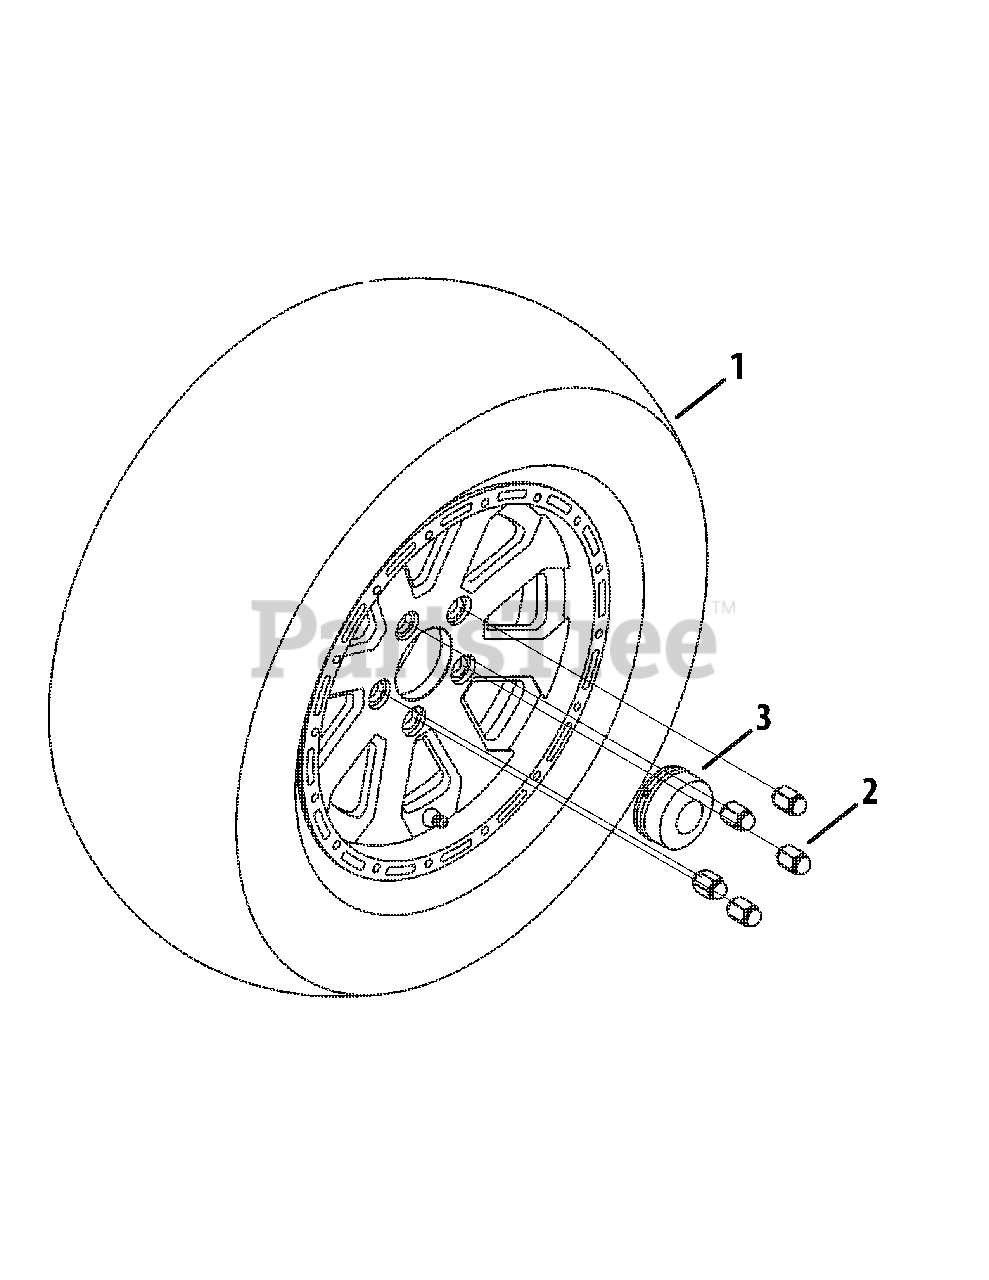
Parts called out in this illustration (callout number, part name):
1	Wheel Assy., 26 x 12-14, Rear/Left
1	Wheel Assy., 26 x 12-14, Rear/Right
1	Wheel Rim, 14 x 8, Rear
1	Tire Only, 26 x 12-14, Rear
1	Wheel Assy., 26 x 10-14, Front/Left
1	Wheel Assy., 26 x 10-14, Frnt/Rght
1	Wheel Rim, 14 x 7, Front
1	Tire Only, 26 x 10-14, Front
2	Nut, Lug, 7/16-14
3	Cap, Wheel
